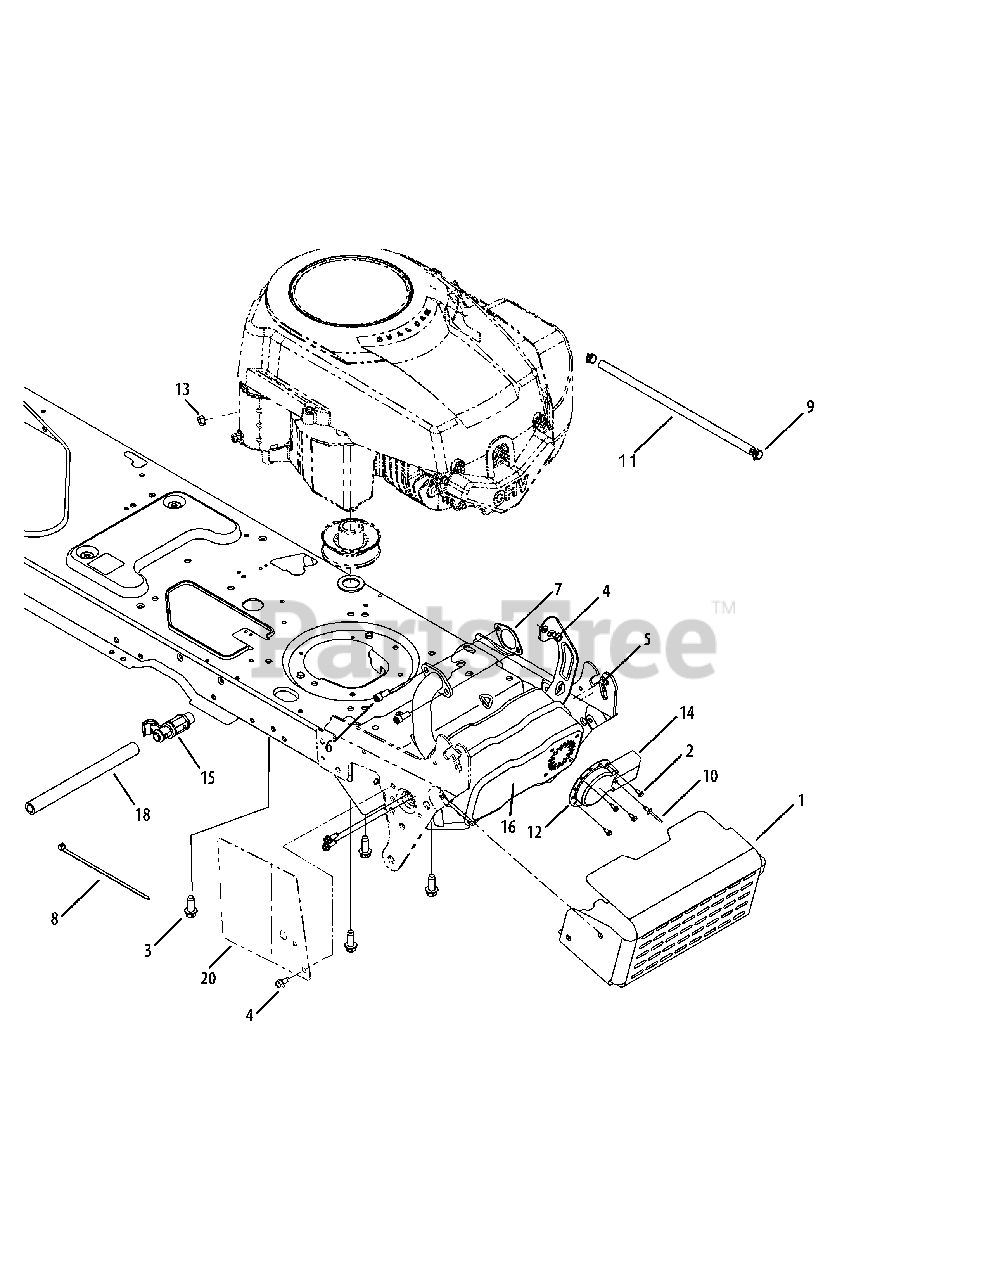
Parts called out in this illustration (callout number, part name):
1	Muffler Shield Assembly
2	Hex AB Scr #8-18 x .50
3	TT Screw 3/8-16 x 1.00
4	Hex Wash S-Tapp Scr 1/4-20 x .50
5	Thd Forming Scr. 1/4-20 x .75 Lg.
6	Scr. 5/16-18 x .75
7	Exhaust Gasket
11	Fuel Line
12	Long Muffler Deflector
13	Hex Sems Nut 1/4-20
14	Muffler Deflector
16	Muffler
18	Oil Drain Hose
